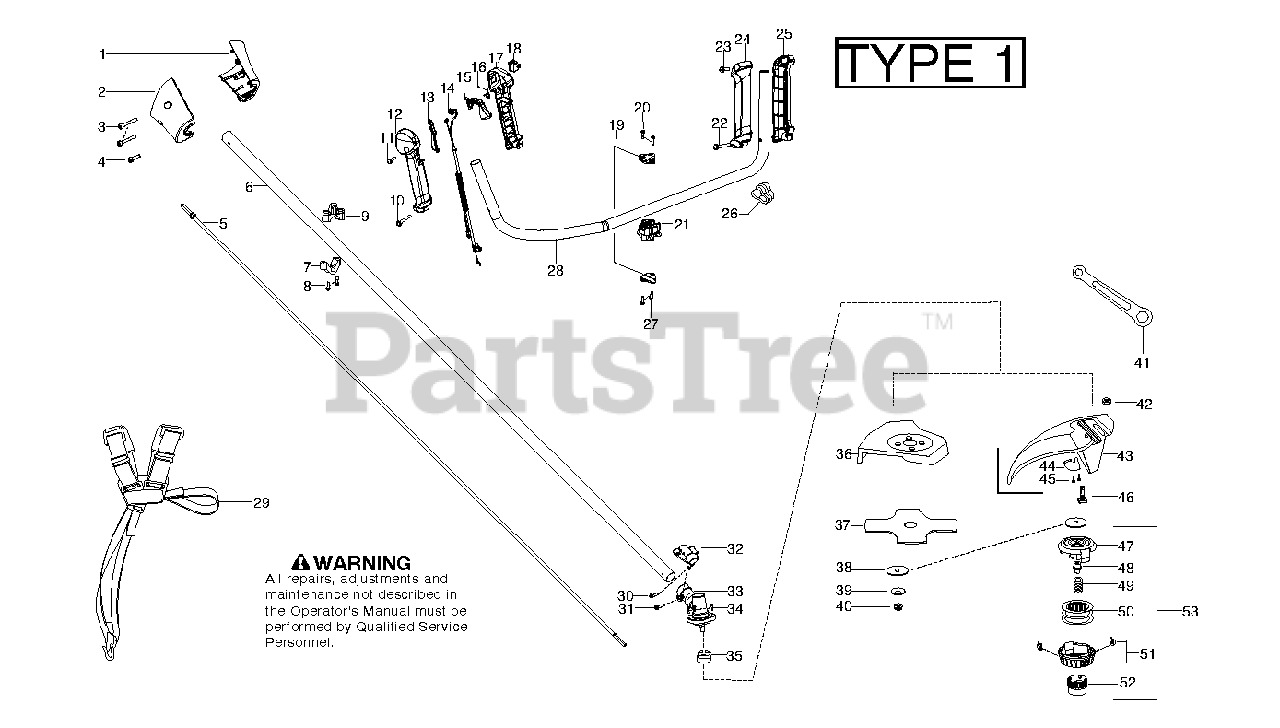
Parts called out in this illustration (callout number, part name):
1	NOSECONE LH LT33 BUL
2	NOSECONE RH LT33 BUL
3	SCREW M4 X 1.75 PT 16MM
4	SCREW-10-16 X 1/2, TYPE 2
5	FLEXSHAFT 57"
6	Drive Shaft Assembly
7	CLAMP HARNESS LOWER
9	CLAMP HARNESS UPPER
10	SCREW #10 PLASTITE 1.362
12	HANDLE HOUSING
13	THROTTLE LOCKOUT
19	CLAMP BRACKET
20	SCREW-10-14 X 13/16 (PL
22	SCREW #10 PLASTITE 1.362
28	ASSY HANDLEBAR BULLH
29	HARNESS BLACK NO LABEL
30	SCREW 8-16 X 9/16 (PLAS
31	SCREW - CARB. ADAPTOR
34	SCR 10-24 MS LDK PAN PH
35	DUST CUP , BLADE
36	KIT
37	ASSEMBLY
38	WASHER,BLADE RETAINING
39	Belleville Washer
40	NUT-FLANGE (LH)
43	KIT
49	SPRING
50	SPOOL WOUND LH 15 FT.
52	KNOB
53	Trimmer Head, P25
